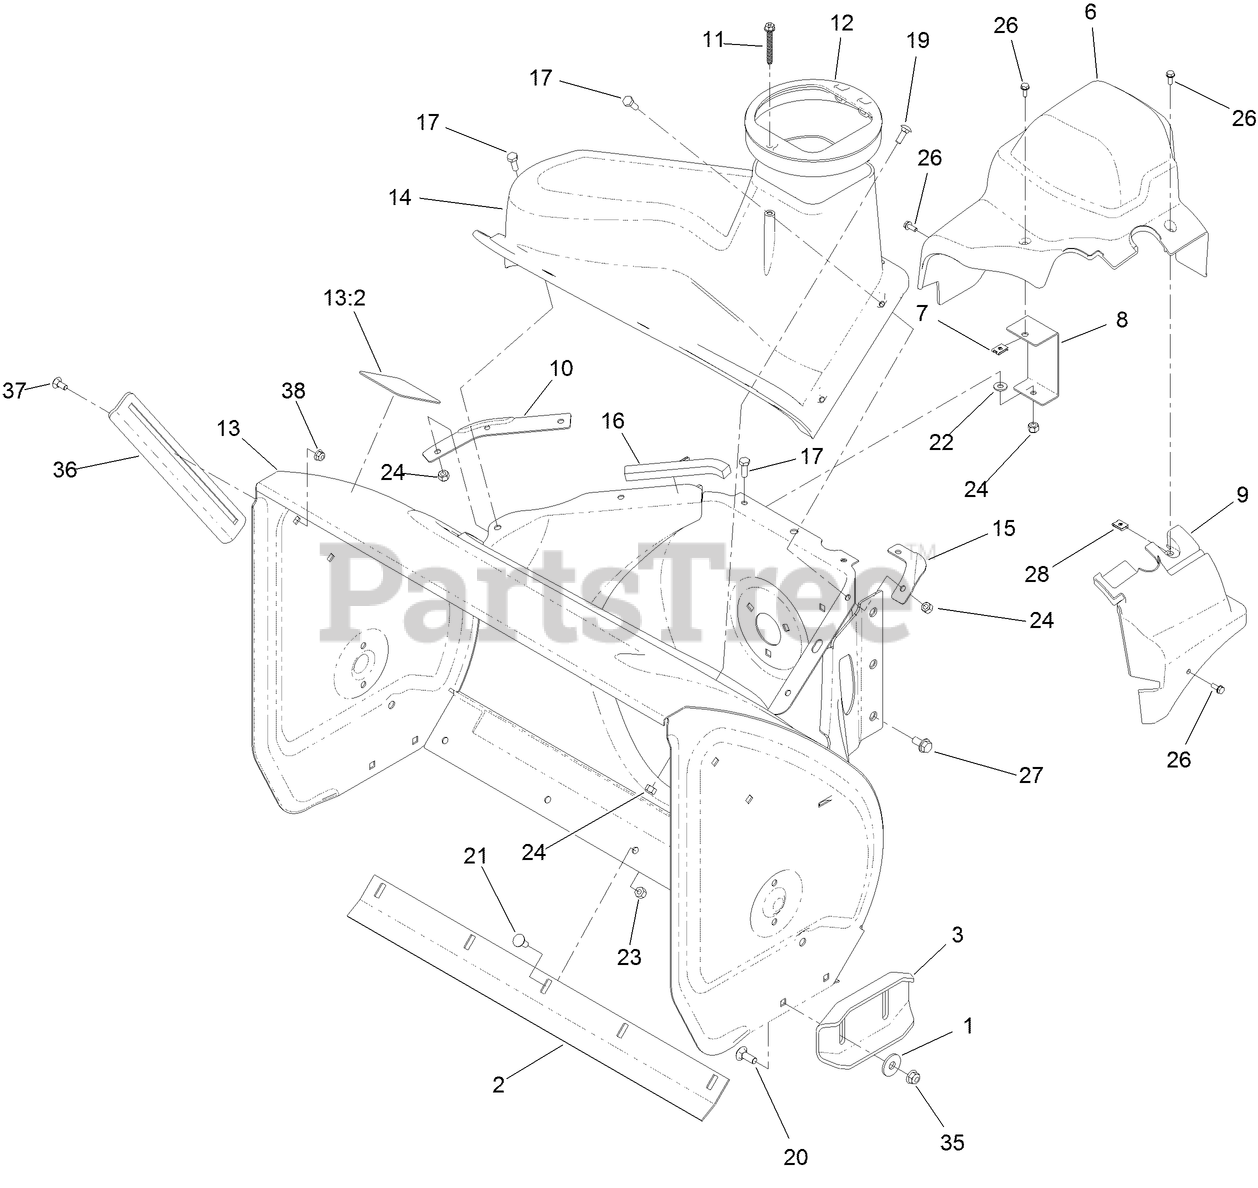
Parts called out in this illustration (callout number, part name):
1	WASHER
2	SCRAPER-FIXED
3	SKID-CAST
6	COVER-BELT
7	NUT-SPEED
8	BRACKET-COVER, CLIP NUT
9	COVER-EXTENSION, BELT
10	SEAL-FLANGE, COVER
11	SCREW-HWH, PLASTITE
12	GUIDE-CHUTE
13	HOUSING-AUGER, 28 INCH
13:2	DECAL-DANGER
16	SEAL-HOUSING
17	SCREW-HH
19	BOLT-CARR
20	SCREW-CARR
21	SCREW-CARR
22	WASHER-FLAT
23	NUT-LOCK, NI
24	NUT-LOCK, NI
26	SCREW-HWH
27	SCREW-HWHTF
28	NUT-SPEED
35	NUT-HF, NI
36	BREAKER-DRIFT, SIDE
37	BOLT-CARR
38	NUT-HF, NI
